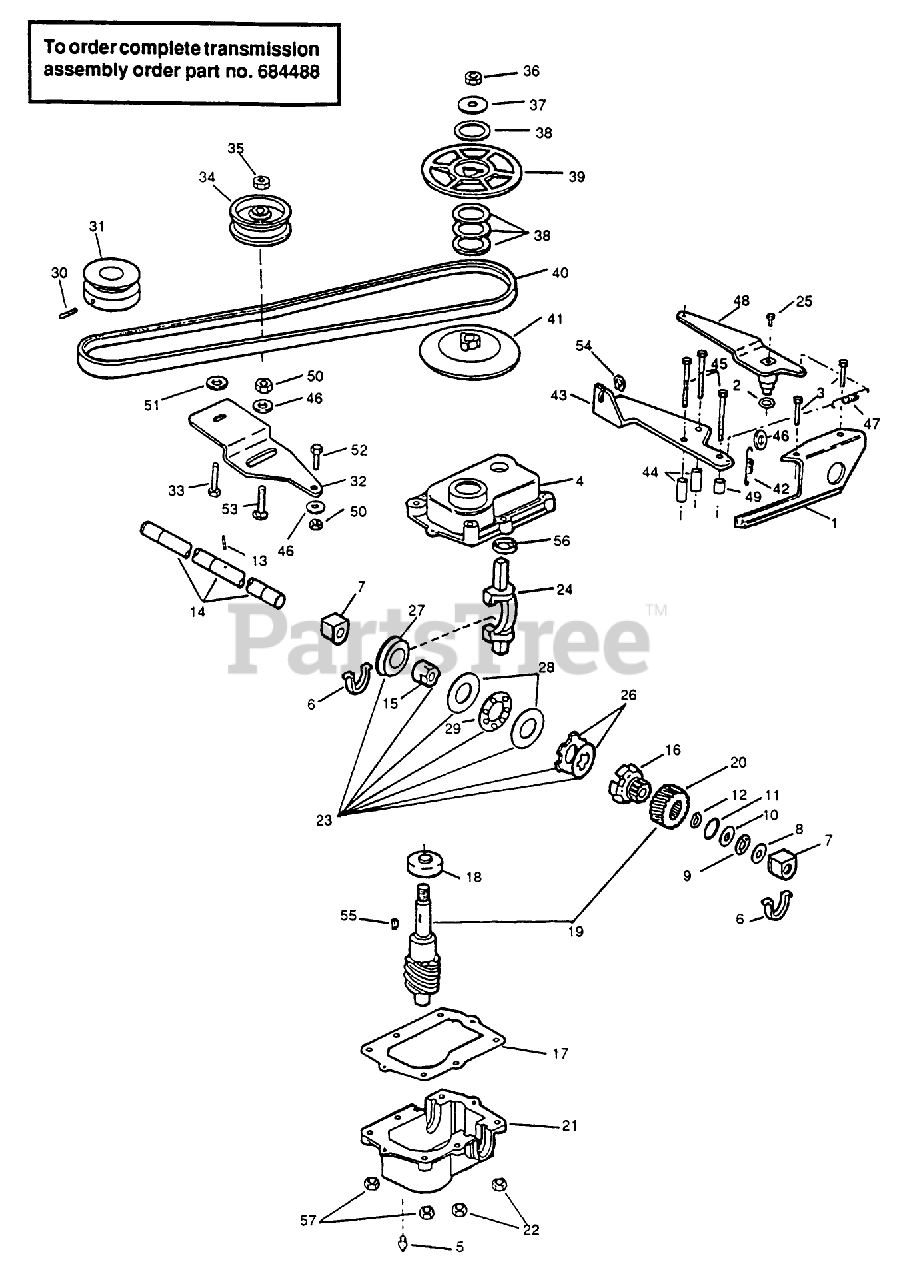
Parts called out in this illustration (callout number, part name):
7	BEARING & SEAL AY (12)
8	THRUST WASHER
10	WASHER-THRUST
12	RET RING
13	PIN DRIVE LOCK
16	DRIVER BROCKWAY
17	GASKET HOOSIER
18	BEARING-BALL
20	WORM WHEEL
22	LOCKNUT E
24	FORK SHIFT
25	SCREW SEMS SM
26	Disc Plate Kit
27	Collar
30	SET SCREW F
31	PULLEY F
34	PULLEY IDLER NHI
35	NUT-JAM, LOCKING
36	LOCKNUT
39	PULLEY UPPER PL
40	V-BELT F
41	PULLEY LOWER PL
42	SPRING EXTEN D&B
43	CONDUIT ANCHOR BRKT
46	WASHER S
50	NUT-LOCK F
54	RET. RING
55	KEY GALGER
56	GUIDE ELCO
57	LOCKNUT E
